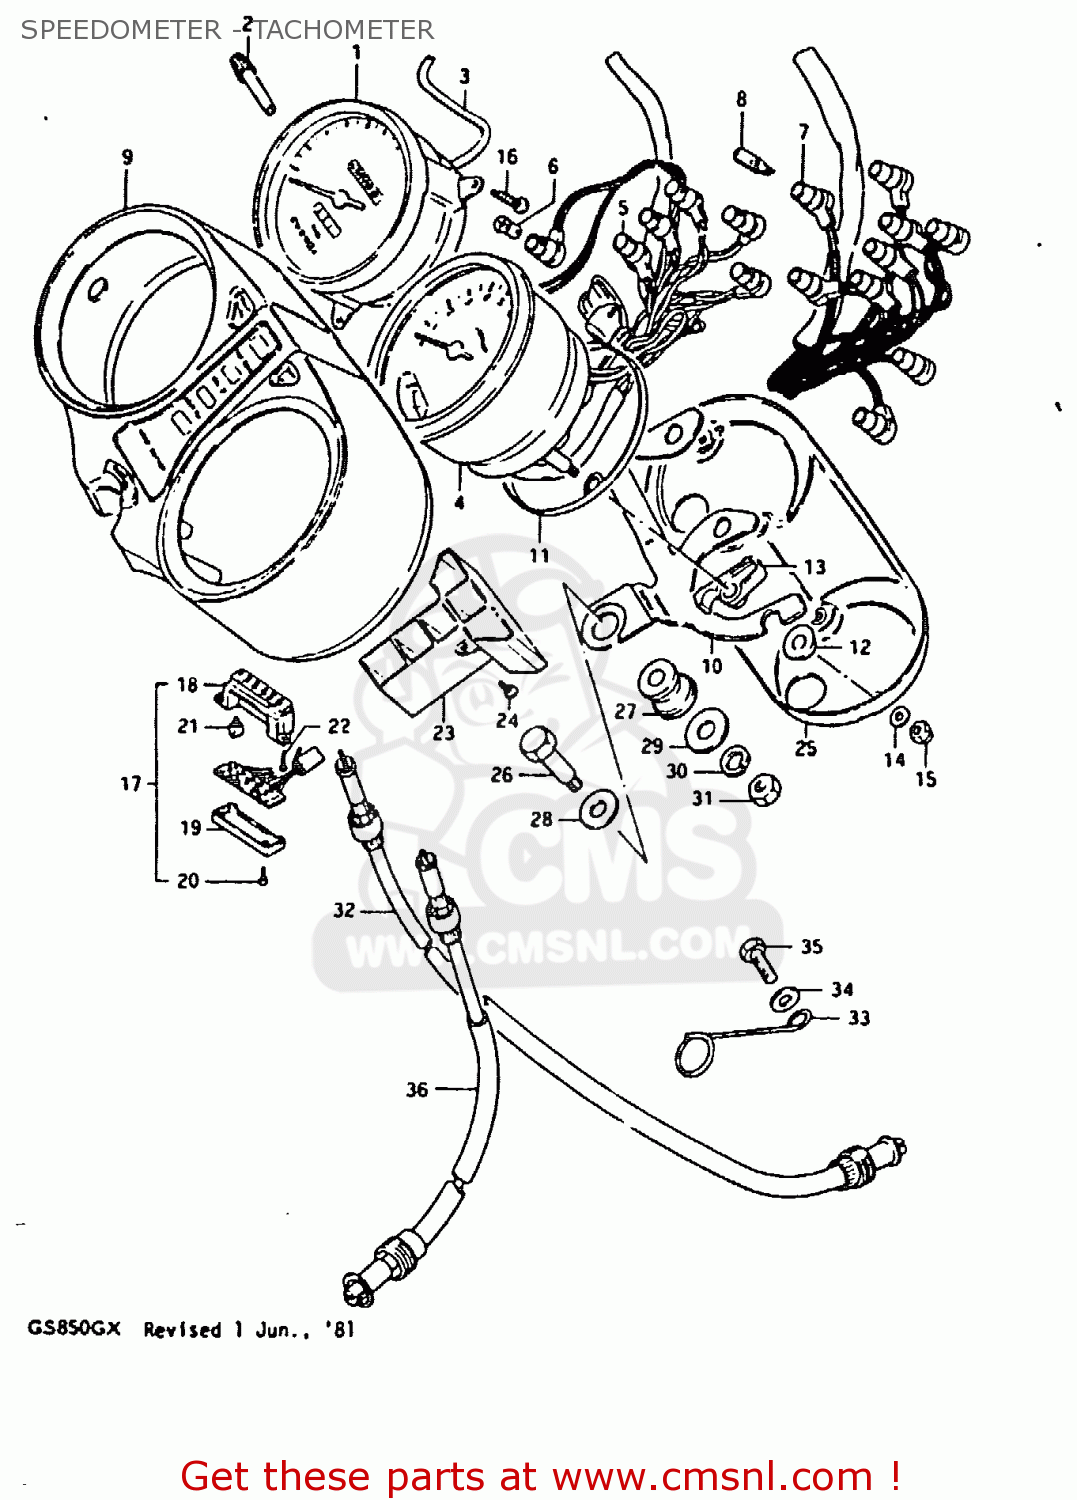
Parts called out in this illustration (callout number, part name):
1	METER,SPEEDOMETER
2	KNOB
3	WIRE,LEAD
4	TACHOMETER
5	SOCKET,METER
6	BULB(12V3.4W,STANLEY,A72A)
7	SOCKET,SPEEDOMETER
8	BULB(12V3.4W,T10)
9	CASE
10	BRACKET,COMBINATION METER
11	PLATE,METER,UNDER
12	CUSHION,METER (A)
13	WASHER
14	WASHER
15	NUT
16	SCREW
17	INDICATOR ASSEMBLY,GEAR POSITION
18	CASE,GEAR INDICATOR
19	COVER,LWR
20	SCREW,GEAR INDICATOR
21	BULB(14V1.12W)
22	SCREW
23	CASE,PILOT BULB
24	SCREW
25	COVER,UNDER
26	BOLT
27	CUSHION,METER
28	WASHER
29	WASHER (8.5X29X1.6)
30	LOCK WASHER
31	NUT
32	CABLE ASSEMBLY,SPEEDOMETER
33	CLAMP,SPEEDOMETER CABLE
34	WASHER
35	BOLT, UPPER
36	CABLE ASSEMBLY,TACHOMETER
